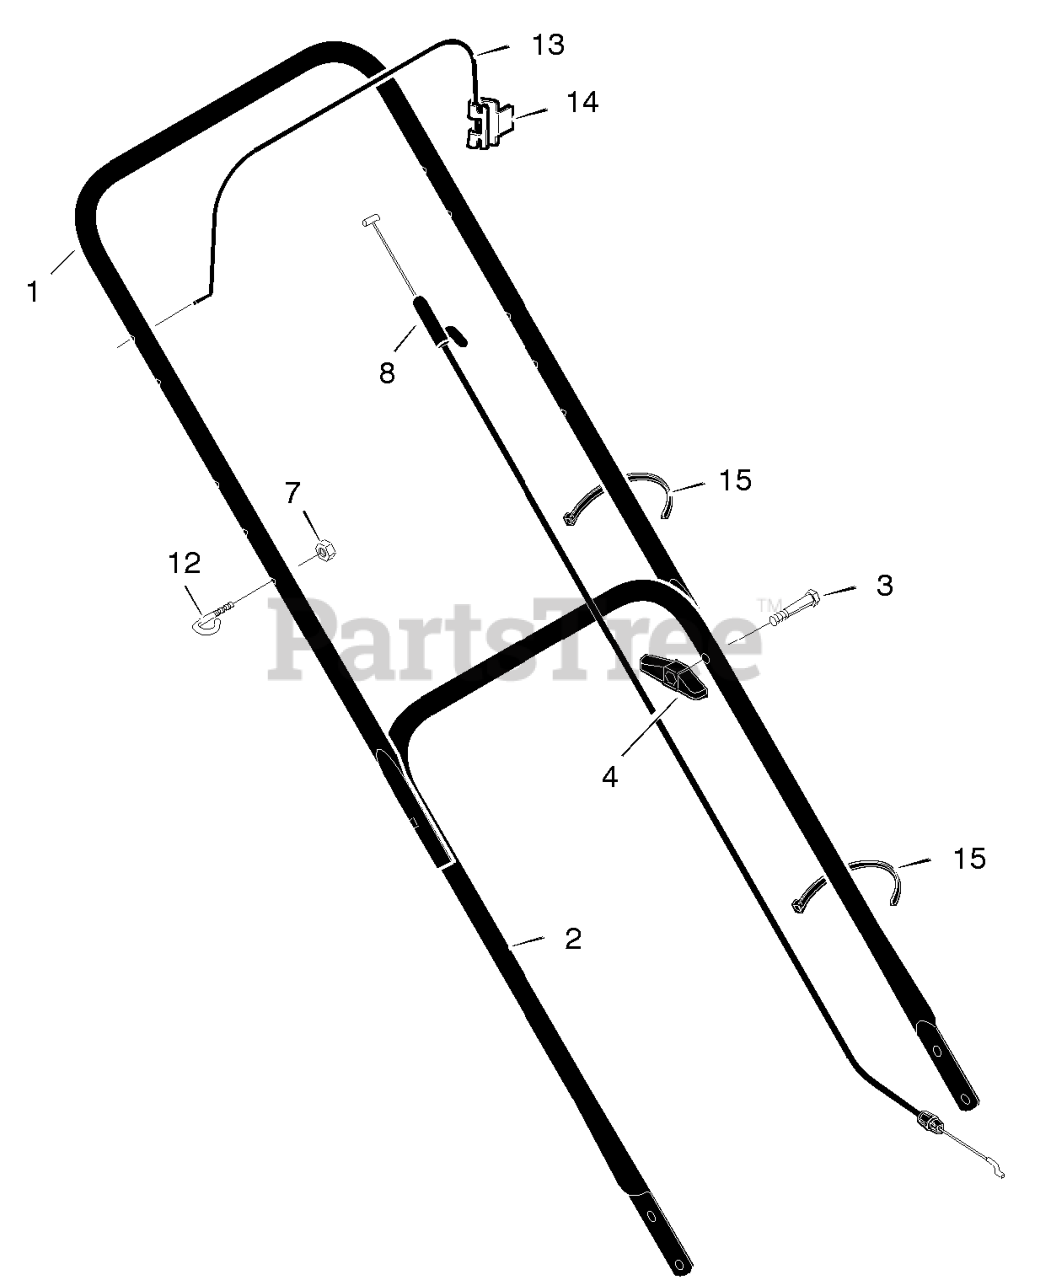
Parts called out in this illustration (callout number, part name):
1	Handle, Upper (Black)
2	Handle, Lower (Black)
4	Knob, Plastic
7	Locknut
8	Engine Stop Cable
12	Guide, Rope
13	Lever, Stop
14	Bracket, Stop Lever
15	Fastener, Cable
